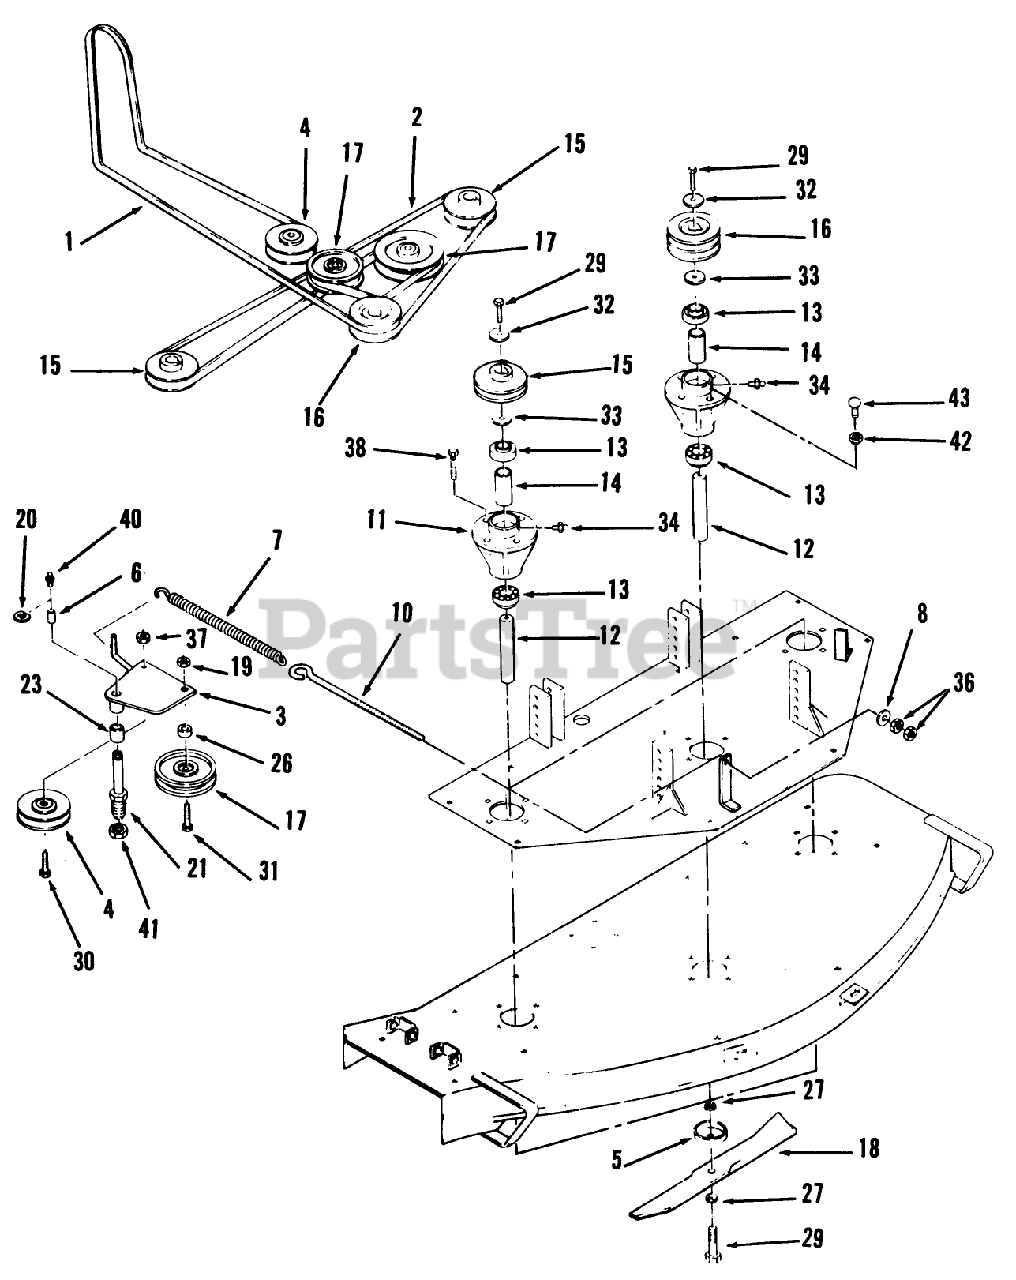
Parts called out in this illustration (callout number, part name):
1	BELT-50" MOW DR 724Z
2	BELT-V
3	WLDMT-IDLER PLATE R
4	PULLEY-IDLER
5	CUP-SPINDLE
6	BUSHING
7	Spring-Idler
8	WASHER-FLAT
10	EYE-BOLT
11	HOUSING-SPINDLE
12	SHAFT-SPINDLE
13	BEARING-BALL
15	PULLEY-OUTER
16	PULLEY-CENTER
17	PULLEY FLAT B
18	MOWER BLADE 17"
19	Carriage Bolt
20	RETAINING RING
21	SHAFT-BELT TEN PI
23	BUSHING
26	SPACER
27	WASHER-SPECIAL
29	Bolt
30	SCREW-HH
31	SCREW-HH
32	WASHER-SPECIAL
33	SPACER
34	FITTING-GREASE
36	NUT-HEX
37	NUT-LOCK, NI
38	SCREW-HH, LOCK
40	Fitting-Grease
41	NUT-LOCK, NI
42	NUT-JAM
43	SCREW-HH
